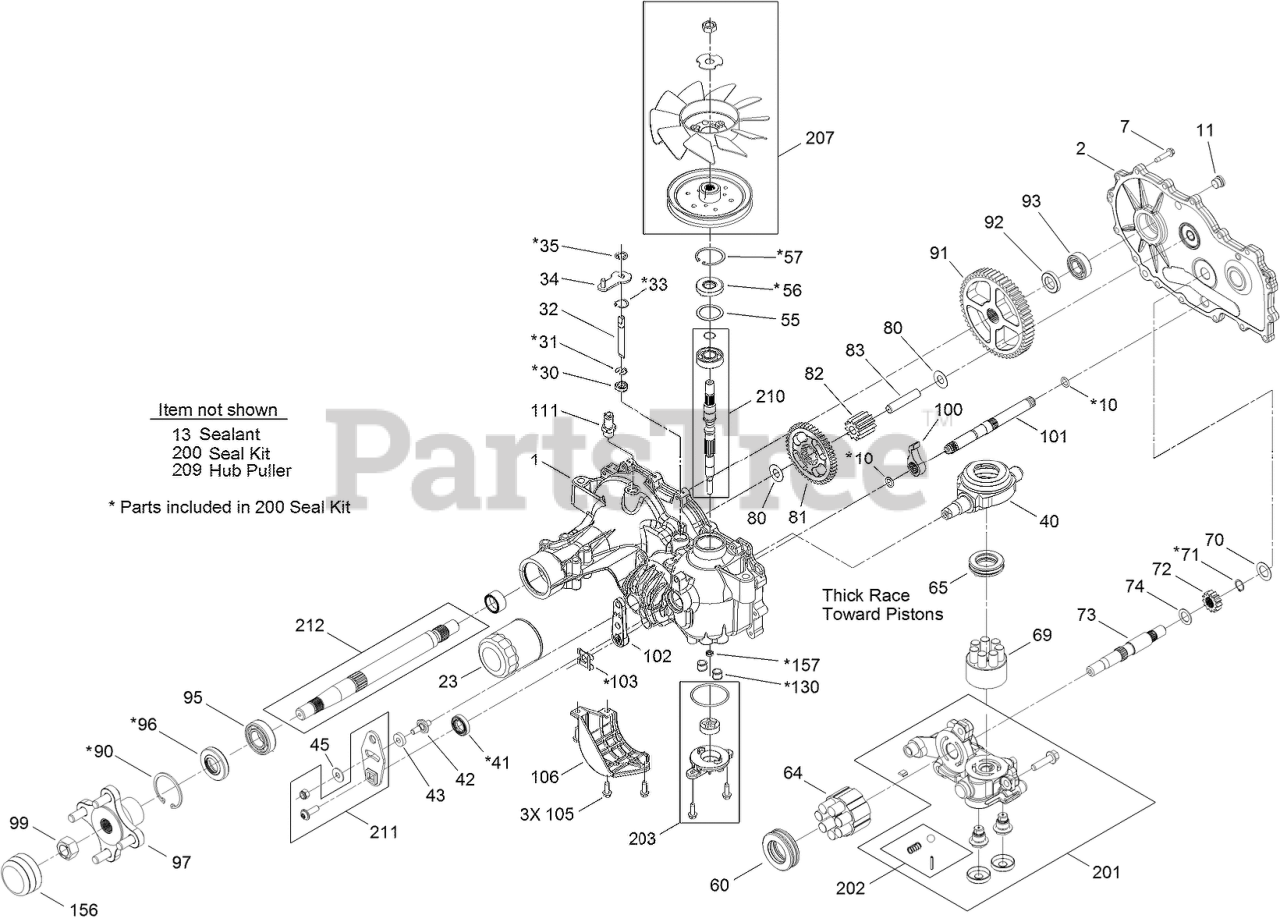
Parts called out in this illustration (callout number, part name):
1	MAIN HOUSING KIT
2	RH HOUSING SIDE KIT
7	SCREW-HHF
10	O-RING
11	PLUG-THREAD, STRAIGHT
23	ELEMENT-OIL FILTER, HYD
30	SEAL-LIP
31	RING-RETAINING, EXTERNAL
32	ROD-BYPASS
33	RING-RETAINING, INTERNAL
34	ARM-BYPASS
35	RING-RETAINING, EXTERNAL
40	SWASHPLATE-TRUNNION
41	SEAL-LIP
43	PUCK-FRICTION
45	WASHER-PIVOT
55	SPACER
56	SEAL-LIP
57	RING-RETAINING
60	BEARING-THRUST
64	MOTOR CYLINDER BLOCK KIT
65	BEARING-THRUST
69	PUMP BLOCK ASM
70	WASHER-FLAT
71	RING-RETAINING
72	GEAR-13T
73	SHAFT-MOTOR
74	WASHER
80	WASHER
81	GEAR-46T
82	GEAR-11T
83	PIN-JACKSHAFT
90	RING-RETAINING
91	GEAR-54T
92	SPACER
93	BEARING-BALL
95	BEARING-BALL
97	HUB KIT
100	PAWL-BRAKE
101	BRAKE SHAFT KIT
102	HANDLE-BRAKE
103	CLIP-RETAINING
106	GUARD-FILTER, RH
111	ADAPTER-STRAIGHT
130	TUBE-CONNECTING
156	COVER-NUT, AXLE
157	SEAL-LIP
201	RH CENTER SECTION CHARGE KIT
202	CHARGE RELIEF KIT
203	CHARGE KIT
207	FAN AND PULLEY KIT
210	INPUT SHAFT KIT
211	CONTROL ARM KIT
212	AXLE SHAFT KIT
